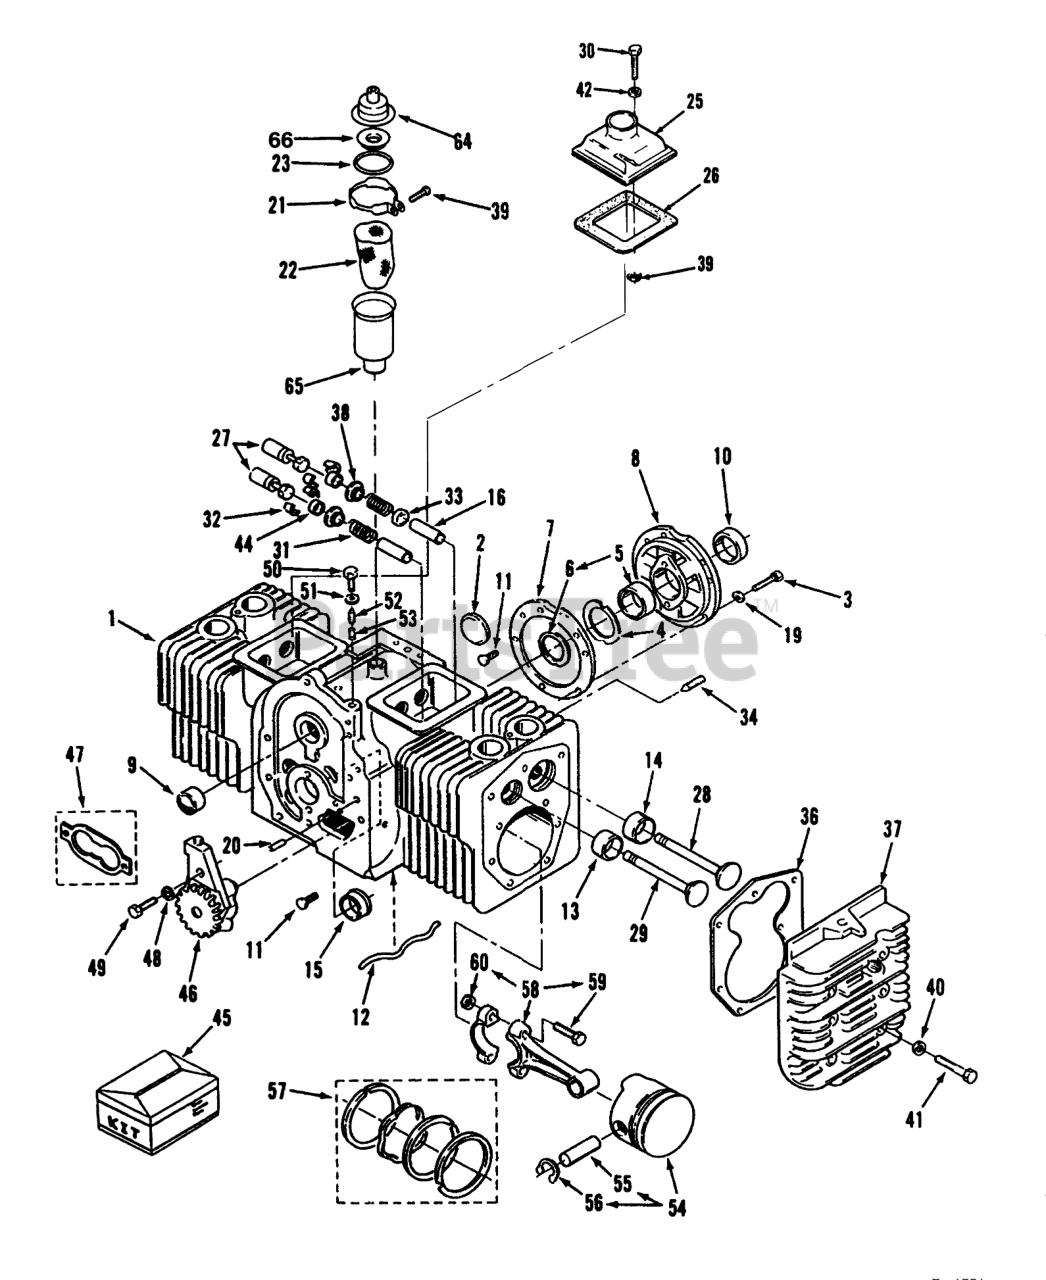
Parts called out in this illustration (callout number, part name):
1	CYLINDER BLOCK
3	HEX HD CAPSCREW
5	BEARING KIT (STANDARD SLEEVE)
6	WASHER
7	Gasket
8	PLATE-BEARING, REAR
9	WASHER
10	SLEEVE-BEARING
11	Screw
12	OIL TUBE
13	Standard
14	Standard
15	Standard
16	Guide-ExhaustValve
19	Washer
20	Pin
21	Clamp
22	FILTER
23	SEAL - O-RING
25	VALVE-COVER L.H.
26	GASKET
27	Tappet
28	Intake Valve
29	Intake Valve
30	HHCS 1/4-20 X 1 3/4
31	Spring
32	VALVE SPRING LOCK
33	Seal
34	Screw
36	Gasket
37	Right Side
38	Washer
39	SCREW-TAPPING, ROUND HEAD
40	WASHER
41	Bolt
42	Washer
44	VALVE CAP
45	ENGINE GASKET KIT
46	Oil Pump
47	Oil Pump Gasket Kit
48	WASHER-FLAT
50	SCREW-HH
51	Washer
52	Spring
53	Piunger
54	Standard
55	Pin-Piston
56	Retaining Ring
57	RING/PISTON KIT
58	CONNECTING ROD W/NUT
59	Rod Bolt
60	Nut
64	BREATHER-CAP AND VALVE
65	TUBE-BREATHER
66	SCREEN-BREATHER TUBE
